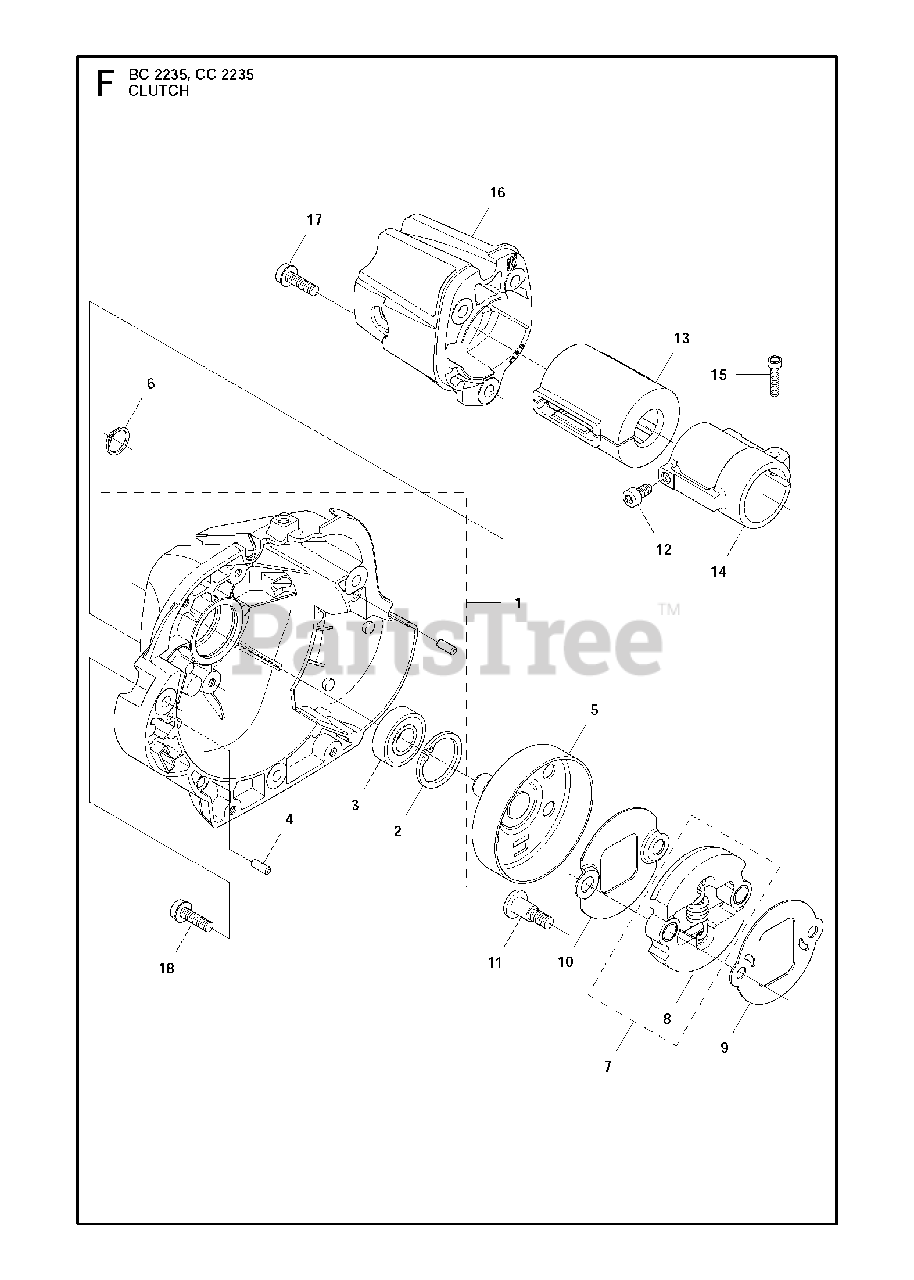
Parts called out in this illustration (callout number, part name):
2	RETAINING RING SGH 28
3	BALL BEARING
4	PIN
5	CLUTCH DRUM
6	SEEGER CLIP
7	CLUTCH CPL
8	SPRING
9	WASHER
11	SCREW CLUTCH
12	SCREW IHSCT
13	VIBRATION ABSORBER
14	SLEEVE, COVER
15	SCREW MC6S 5X25
18	SCREW CLUTCH
